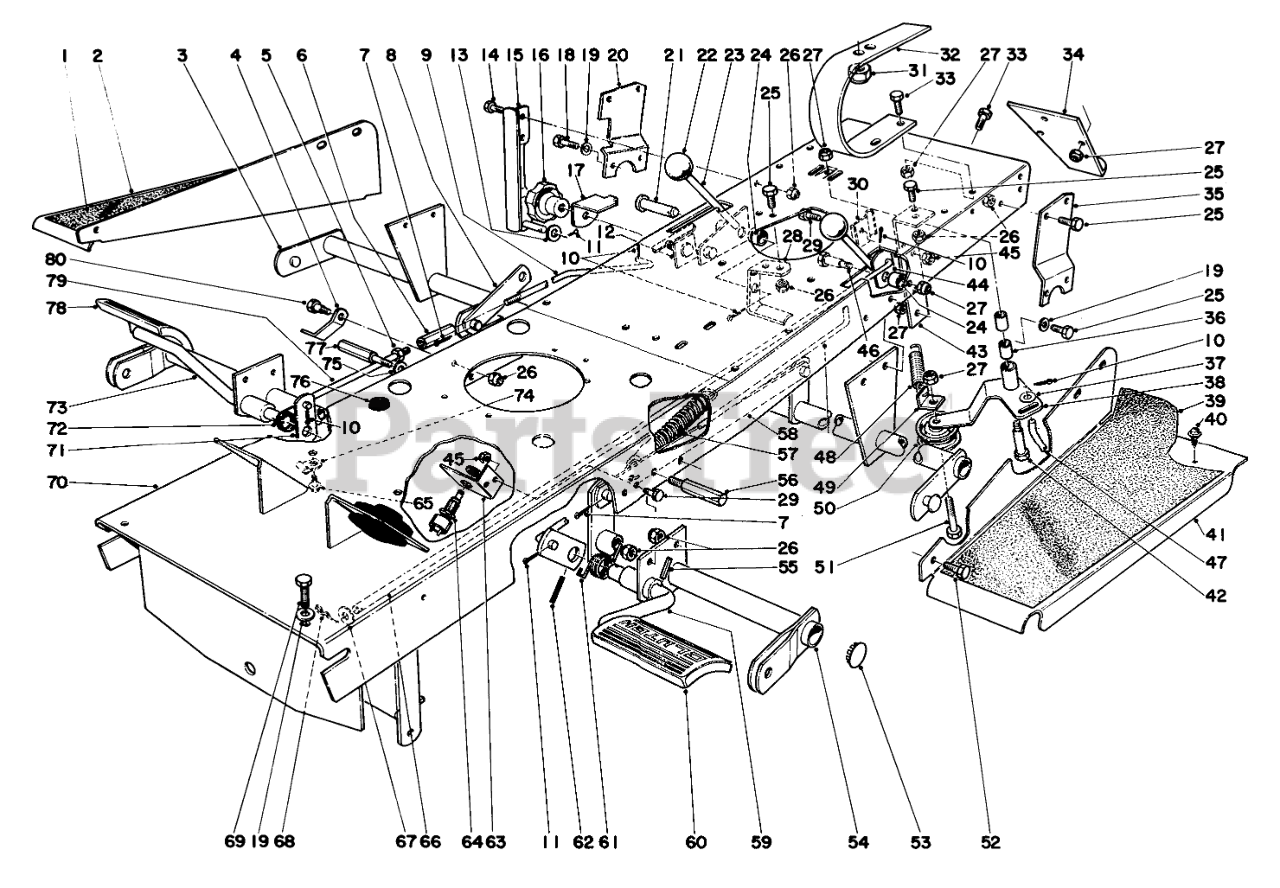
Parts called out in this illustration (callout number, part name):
1	Pad R. H.
2	Footrest R.H.
3	Cross Tube
4	Pedal Latch
5	NUT-JAM
6	Screw Brake Adjusting
7	PIN-COTTER
8	Lift Link
9	Brake Rod Rear
10	PIN-COTTER
11	PIN-COTTER
12	Knob Plate
13	WASHER-FLAT
14	SCREW-HH
15	Support Hanger Brake
17	Slide
18	SCREW-HH
19	WASHER-LOCK
20	Support R.H.
21	Clevis Pin
22	Knob
23	Lever
24	Spacer
25	SCREW-HH
26	NUT-LOCK, CONE
27	NUT-LOCK, CONE
28	Support Guide
29	SCREW-HH
30	Belt Guide
31	1/2-13 CONELOCK NUT
32	Seat Spring
33	SCREW-HH
34	Hitch
35	Support Left
36	BUSHING
37	WASHER-FLAT
38	Idler Arm Incl. Ref. #36
39	Pad Left
40	10-16 X 3/8 THDG SCREW
41	Footrest
42	Shoulder Bolt
43	Support Transaxle
44	Lever
45	NUT-LOCK, CONE
46	Shoulder Bolt
47	Clutch Rod
48	Tension Spring
50	Idler Pulley
51	SCREW-HH
52	SCREW-HH
53	Plug Button
54	Cross Tube Front
55	PIN-SPRING
56	Pedal Stop
57	Spring Counterbalance
58	Lift Equalizer
59	Pedal L.H.
60	CLUTCH PAD
61	Pedal Return Spring
62	PIN-ROLL
63	Mounting Bracket
64	Switch Spno
65	10-16 X 3/8 THDG SCREW
66	Rod Clutch
67	WASHER-FLAT
68	PIN-COTTER
69	He Ha. Screw
70	Frame
71	Lever Pedal Shaft
72	Pedal Return Spring
73	Pedal R.H.
74	Clamp-Cable
75	Washer
76	GROMMET
77	Brake Stop
78	PAD-BRAKE
79	Brake Rod Front
80	Shoulder Bolt
